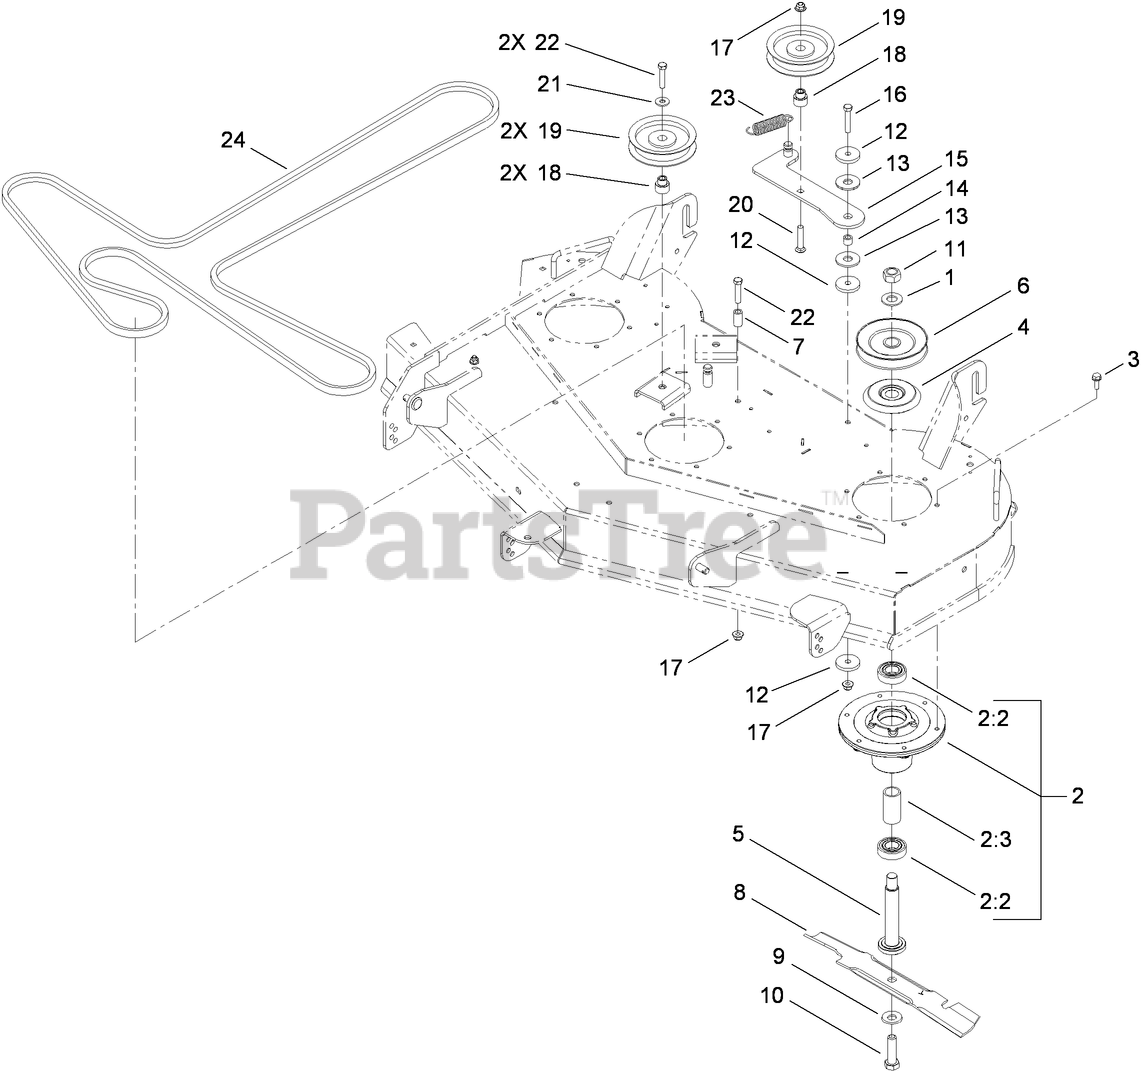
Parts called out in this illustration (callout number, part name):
1	WASHER
2:3	SPACER-BEARING
3	SCREW-TAPTITE
4	SHIELD-BEARING
5	SHAFT-SPINDLE
6	PULLEY
7	SPACER
8	BLADE-HI FLO, 16.50 INCH
10	SCREW-BLADE
11	NUT-HEX
12	WASHER-PLAIN
13	WASHER-FRICTION, COMPOSITE
14	BUSHING-LEVER, LIFT
15	ARM-IDLER
16	SCREW-HH
17	NUT-HF, NI
18	BUSHING-IDLER
20	SCREW-CARR
21	WASHER-HARDENED
22	SCREW-HH
23	SPRING-EXTENSION
